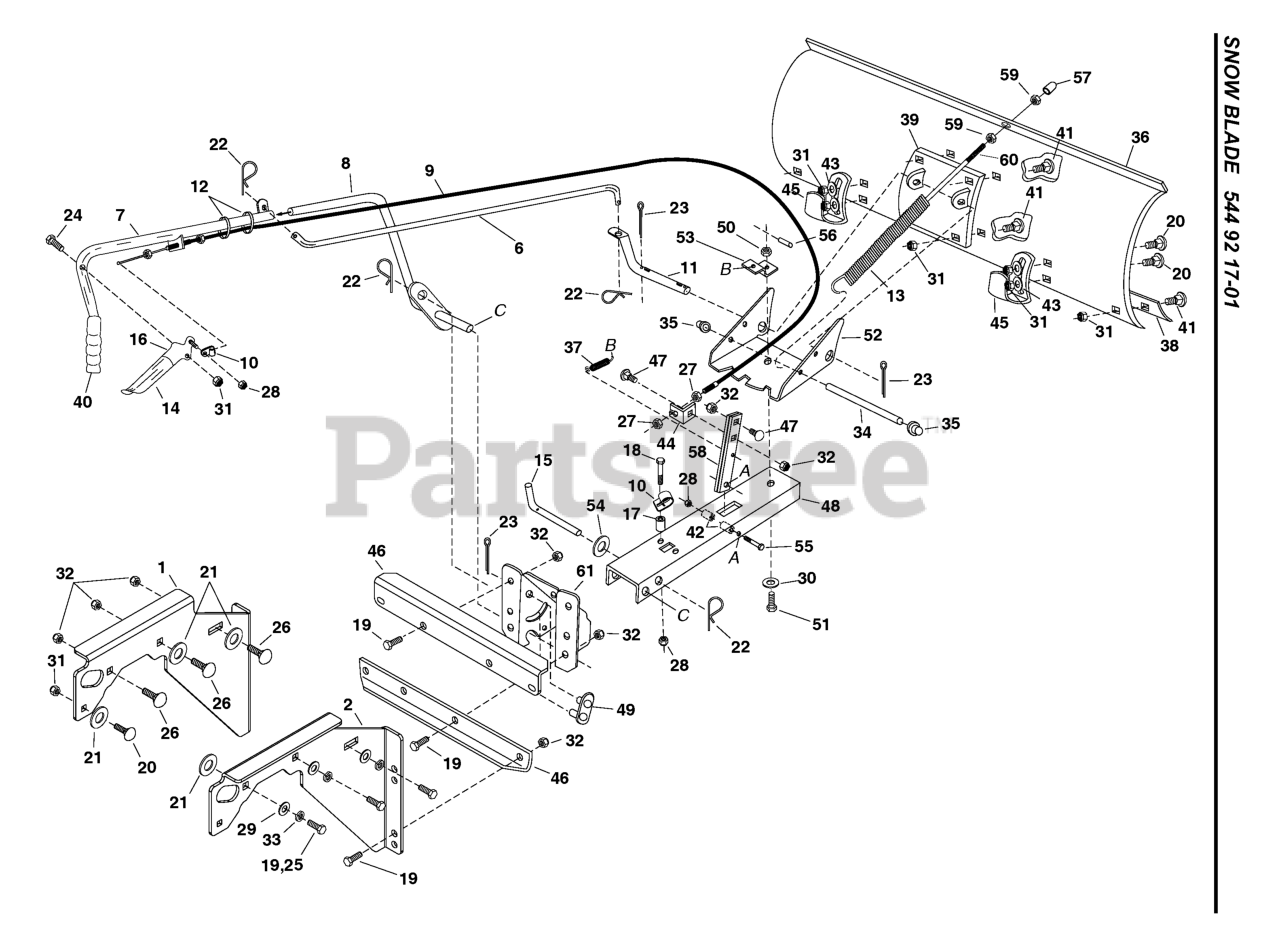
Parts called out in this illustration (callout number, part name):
1	BRACKET 25645
2	BRACKET 25646
7	TUBE 65516
10	CABLE 746-0260
11	SHAFT 46066
12	TIE WRAP 726-0178
13	SPRING R9466R
14	GRIP 731-0869
16	GRIP 62561
17	SPACER 23658
18	Hex Head Capscrew, M6 X 1.00 X 40MM
21	WASHER R19172410
25	BOLT 47631
26	BOLT 43350
27	NUT 712-0256
29	WASHER
30	WASHER 1540-118
33	Spring Washer
36	SNOW BLADE 23955
37	SPRING 43348
38	WEAR PROTECTION
39	PLATE 62980
40	GRIP 46471
41	RP BOLT 5/16-18 X3/4 ZN/YEL GR
42	SPACER 46053
43	WASHER BRB 8.4X17
44	BRACKET 05762
45	SKID PLATE
46	BRACKET 25647
47	BOLT 710-0305
48	FRAME 24347
49	LINK 63034
51	BOLT 23131
52	PLATE 23958
53	BRACKET 23130
55	BOLT 46071
57	HUB CAP 44074
60	BOLT 44071
61	BRACKET 24023
